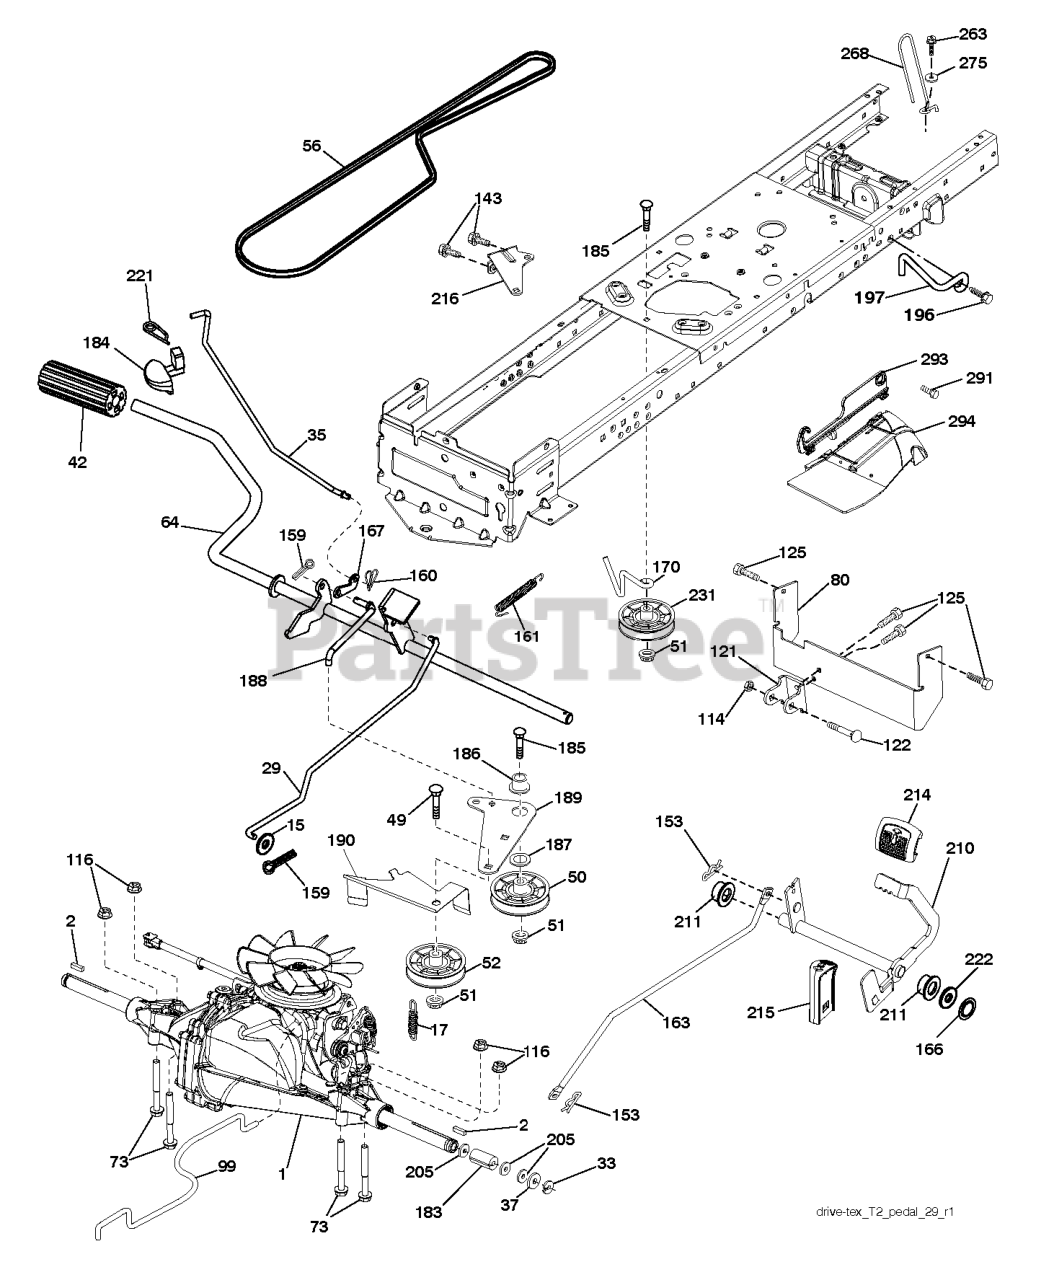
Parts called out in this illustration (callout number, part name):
2	SQUARE KEY
15	WASHER
17	SPRING.BRAKE.HG3000/3500
29	ROD.BRAKE.T2.TEX
35	ROD.CNTRL.PARK.PREDATOR.LT.TEX
42	PEDAL COVER T
50	IDLER.FLAT.910.OFFSET
51	NUT LOCK FLG 3/8-16 UNC
52	IDLER.V-GROOVE.910.OFFSET
64	SHAFT.ASM.PEDAL.BRK.CNTR
73	BOLT HEX 5/16-18 GR 5
80	RP.STRAP.TORQUE.FS.T2
99	ROD.ASM.BYPASS.SPRING.T2.FS
114	NUT.71038.31-18.HEX.NYLOCK
116	NUT LOCK HEX FLANGE 5/16-18
121	BRACKET STRAP TORQUE
122	BOLT.5/16-18X2.5
125	SCREW
143	SCREW LT
153	RETAINER M
159	COTTER PIN
160	RETAINER CLIP
161	SPRING, RETURN LT
163	ROD.CONTROL.PCH.T2.TEX
166	NUT.PUSH.625
167	LATCH.BRAKE.SPRING
170	KEEPER.CENTER SPAN.1.688
183	SPACER, AXLE PVST
184	HANDLE.PARKING.BRK.PRED.LT.RED
186	SPACER.RETAINER
187	WASHER 12/32X2X10GA
188	RP.LINK.CLUTCH.GROUND.DRIVE
189	BELLCRANK.GROUND.DRIVE.TEX.
190	KEEPER.BELLCRANK.DRIVE
196	SCREW 3/8-16X1
197	LINK.CLUTCH.ANIT-ROTAT
210	ROCKER.ASM.PEDAL.CONTR
211	BEARING.NYLON
214	PEDAL.FORWARD.PAD.TEX
215	PEDAL.REVERSE.TEX.GT.4
216	BRACKET.PULLEY.IDLER.W/TEX
221	RETAINER.SPRING.CLIP.H
222	WASHER 21/32 X 1-1/4 X 10 GA.
231	IDLER.V-GROOVE.1.688.OFFSET
263	SCREW, 3/8-16X3/4
268	GUARD MUFFLER
275	WASHER
291	SHOULDER BOLT 5/16-18TT
293	HINGE RIGHT
294	GUARD RIGHT
